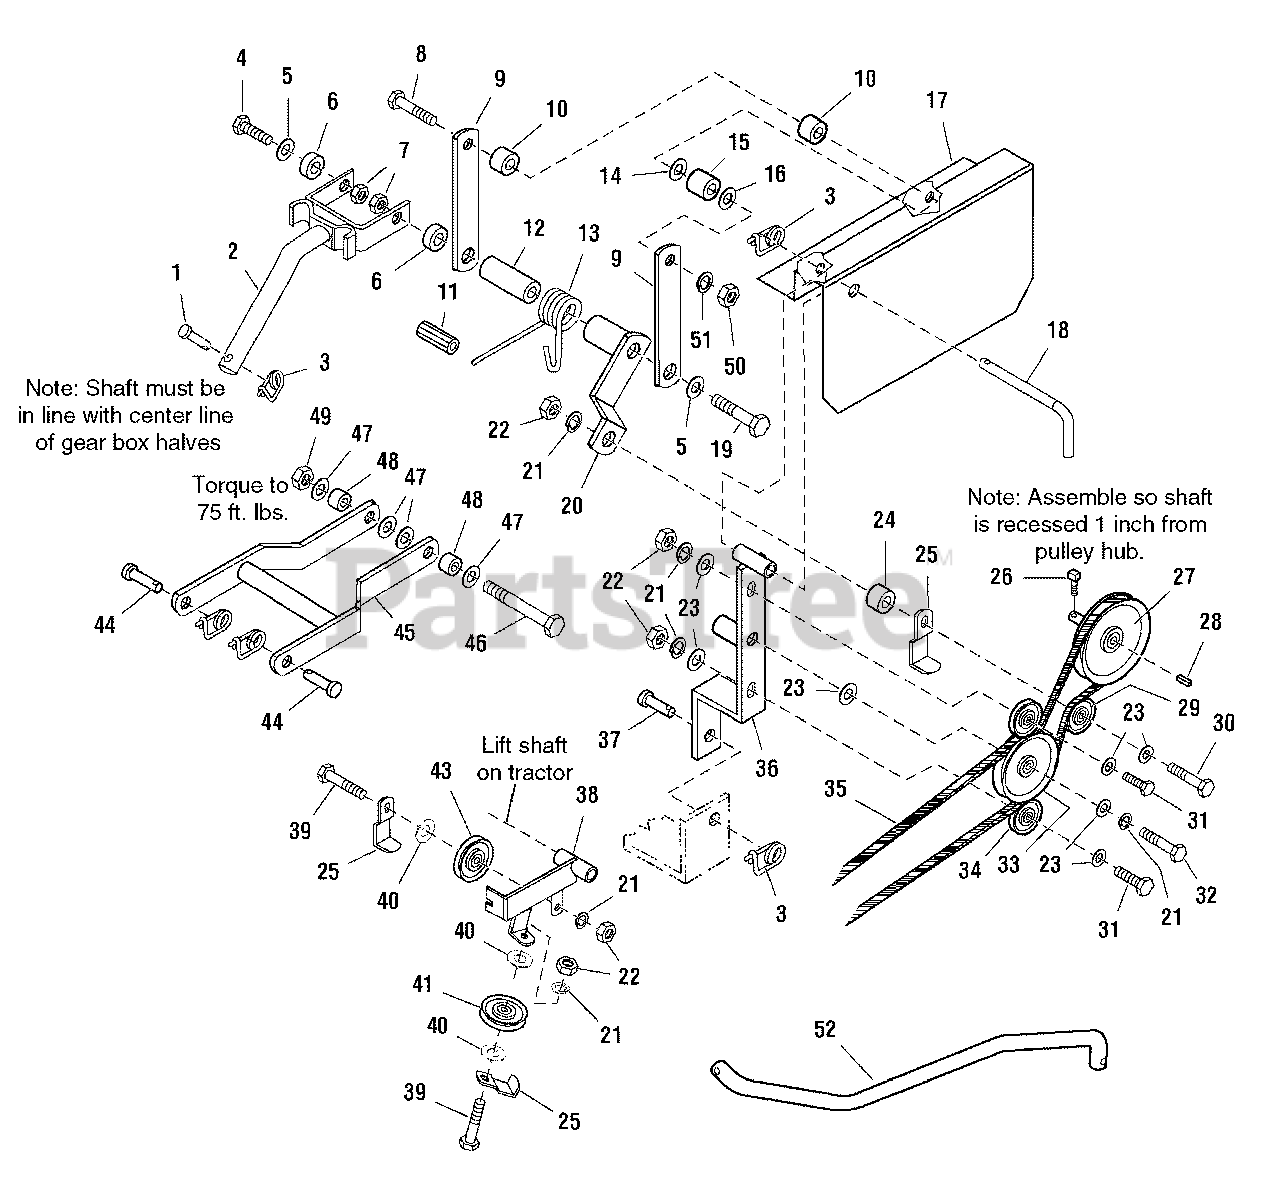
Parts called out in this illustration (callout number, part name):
1	PIN, Round Head Drilled, 3/8 x 2, Black
2	LIFT ASSEMBLY
3	PIN, Spring Retainer
4	CAPSCREW, Hex Head, 7/16-14 x 1-1/4, Black
5	WASHER, 7/16
6	SPACER
7	NUT, Hex Flange Lock, 7/16-14, Black
8	CAPSCREW, Hex Head, 5/16-18 x 2-3/4, Balck
9	SUPPORT, Rear Belt Guard
10	SPACER
11	ANCHOR, Spring
12	SPACER
13	SPRING, Torsion
14	WASHER, Special, Nylon
15	BUSHING, .343" x .750" x 1.060"
16	WASHER, 5/16, Black
17	COVER, Belt
18	ROD
19	CAPSCREW, Hex Head, 7/16-14 x 3-1/2, G8
20	ARM & HUB ASSEMBLY
21	LOCKWASHER, 3/8, Black
22	NUT, Hex, 3/8-16, Black
23	WASHER, 3/8, Black
24	SPACER
25	GUARD, Spring
26	SCREW, Set Square Head, Cup Point, 3/8-16 x 1/2
27	PULLEY, 7.96" OD x .752" ID, w/.562" GROOVE, w/HUB
28	KEY, Parellel
29	PULLEY, Idler, 2.75" OD x .377" ID x .87 WD
30	CAPSCREW, Hex Head, 3/8-16 x 3-1/2, Black
31	CAPSCREW, Hex Head, 3/8-16 x 2-1/4, Black
32	CAPSCREW, Hex Head, 3/8-16 x 1-1/4, Black
33	PULLEY, Idler, 4" OD x .375" ID x .83" WD
34	PULLEY, Idler, 1.875" OD x .375" ID x .97" WD
35	V-BELT,167.40" Long
36	SHAFT & SUPPORT ASSEMBLY
37	PIN, Round Head Drilled, 3/8 x 1, Black
38	ARM ASMY-IDLER TILLER
39	CAPSCREW, Hex Head, .375-16 x 1.750 G5 BLK
40	WASHER, 3/8, Black
41	PULLEY, Idler, 3.125" OD x .669" ID x 1WD, w/Bearing
43	PULLEY, 3" OD x .378" ID x .75" WD, w/Bearing
44	PIN, Round Head Drilled, 7/16 x 1-3/4
45	FRAME ASSEMBLY
46	CAPSCREW, Hex Head, 1/2-13 x 5, G8 Black
47	WASHER, 1/2, Black
48	SPACER
49	NUT, Hex Flange Lock, 1/2-13, Black
50	NUT, Hex, 5/16-18, Black
51	LOCKWASHER, 5/16, Black
52	ROD, Diff Lock, 15" Long
